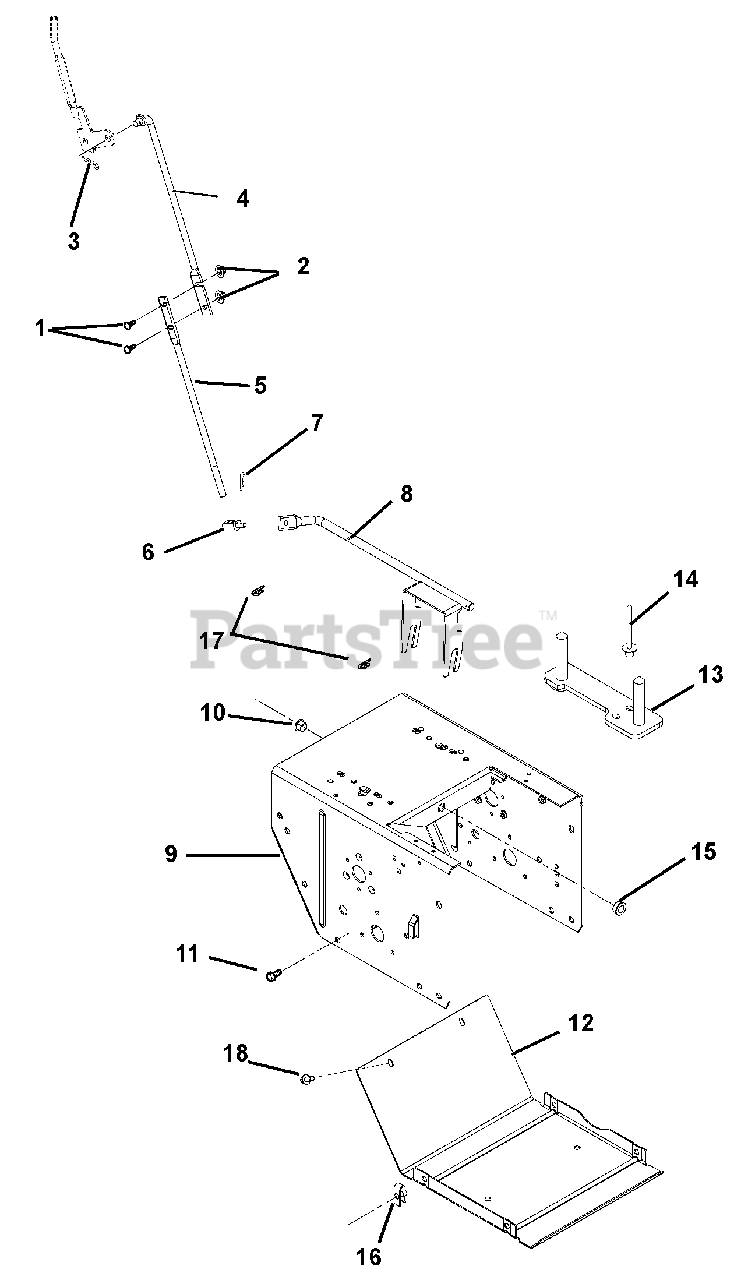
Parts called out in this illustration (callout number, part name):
1	Bolt, Round Head Square Neck .25-20 x .75 Grade 5
2	Nut, Locking Wing .25-20
3	Pin, Hair #25
4	Rod, Shift-Upper
5	Rod, Shift-Lower
6	Pivot, Shift Rod
7	Pin, Hair #25
8	Arm, Shift Weldment
9	Main Frame
10	Bushing, Polyliner .50 Split
11	Bolt, Hex Washer Head .25-20 x .75
12	Cover, Bottom
13	Bolt Strap
14	Rivet, Pop
15	Bushing, Polyliner .50 Snapin
16	Nut-Retainer .25-20 x .56
17	Clip, Spring
18	Screw, Tapping .25-20 x .50 Hex Washer Head
